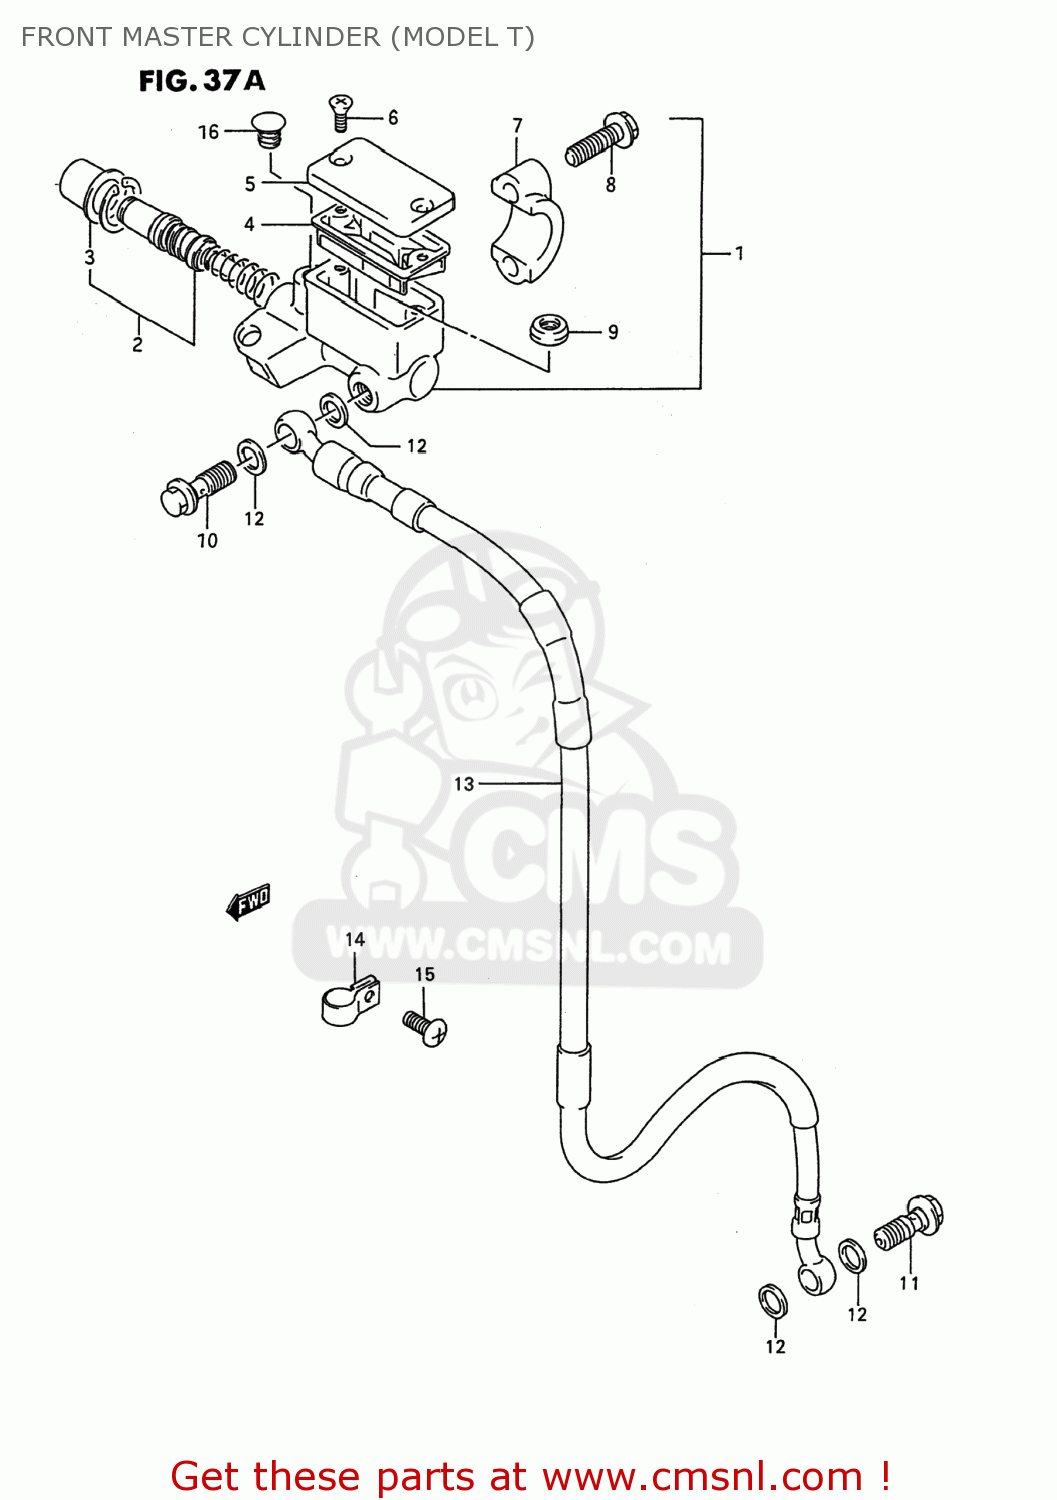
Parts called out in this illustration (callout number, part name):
1	CYLINDER ASSEMBLY,FRONT MASTER
2	PISTON & CUP SET
3	BOOT
4	DIAPHRAGM
5	CAP
6	SCREW
7	HOLDER
8	BOLT
9	SEPARATOR
10	BOLT UNION
11	BOLT UNION
12	WASHER(10X15X1.5)
13	HOSE COMP,FRONT BRAKE
14	CLAMP,FR BRAKE
15	SCREW
16	CAP(OD:14)
